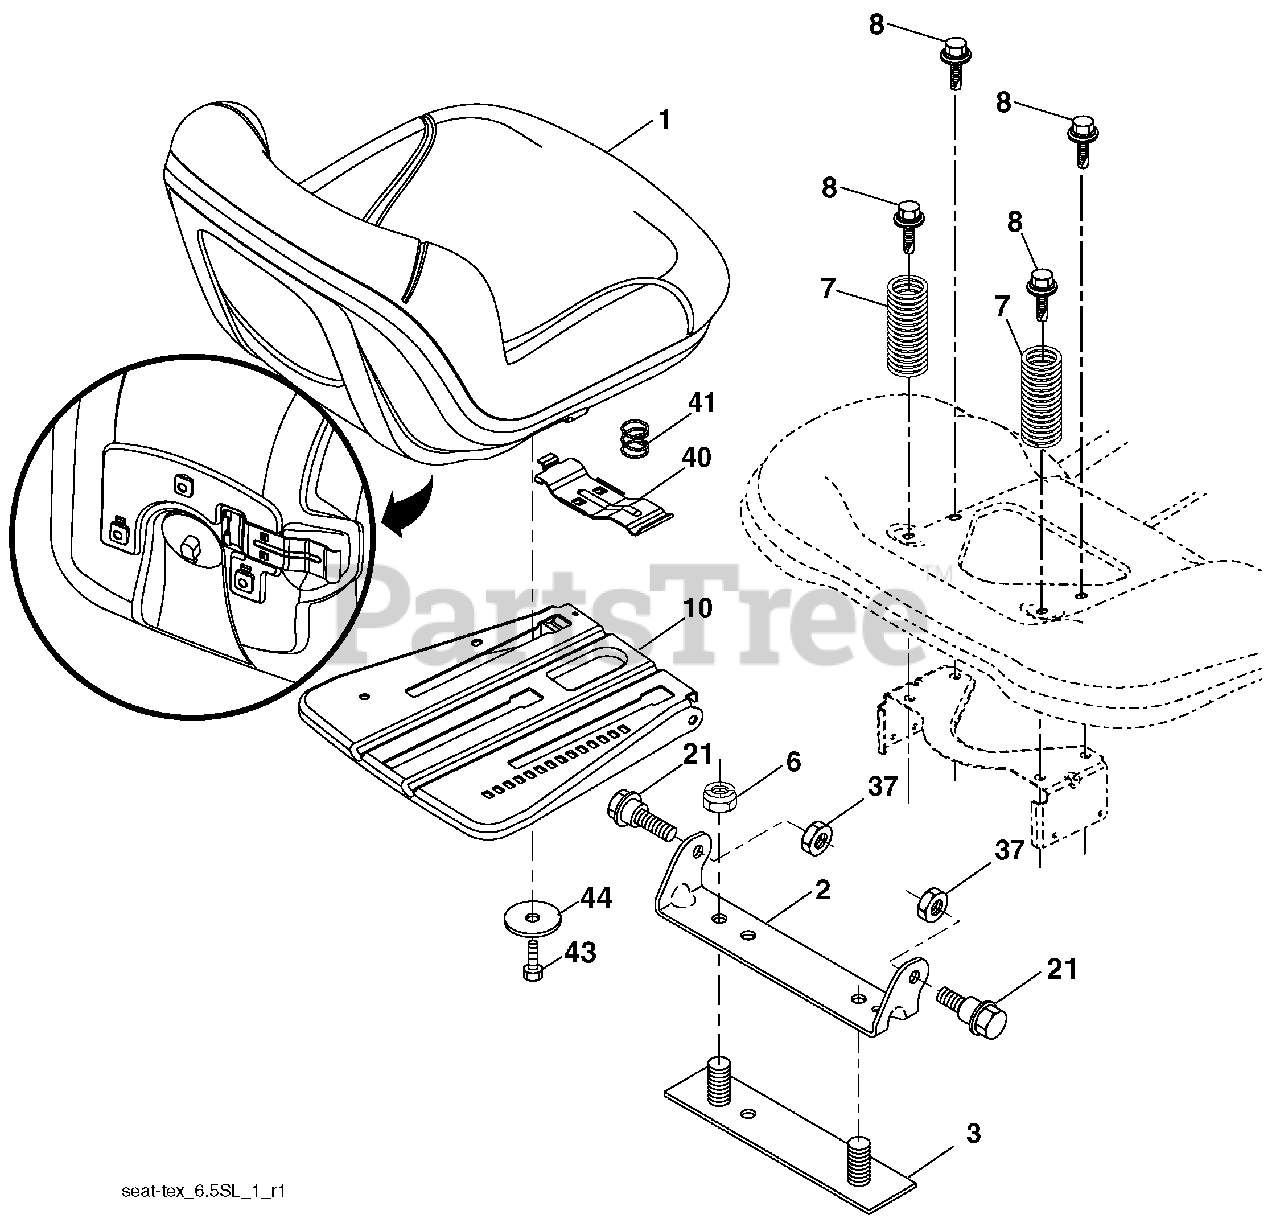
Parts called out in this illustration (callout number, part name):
1	Seat
2	Bracket Pivot Fender
3	Strap, Asm Fender
6	Nut, Lock w/Ins. 3/8-16 unc
7	Spring, Seat Cprsn
8	Bolt 5/16-18 unc x 3/4 w/Sems
10	Pan, Seat
21	Bolt, Shoulder 5/16-18
37	Nut, Lock 5/16-18 unc
40	Handle Slide Seat
41	Spring Latch Seat
43	Bolt Fin Hex 3/8-16 unc x 3/4
44	Washer 13/32 x 2-3/8 x 12 Ga.
